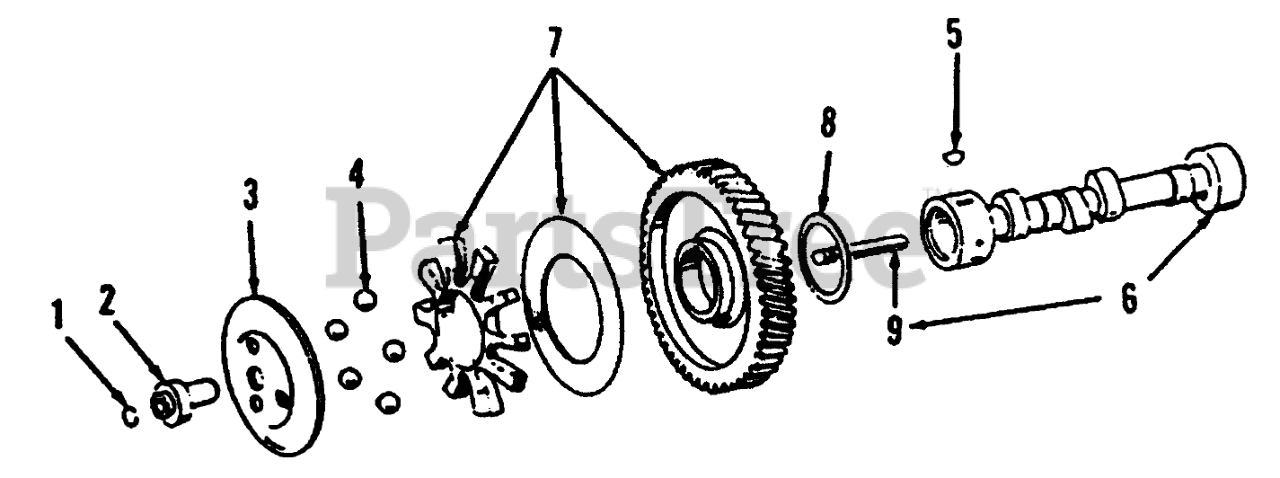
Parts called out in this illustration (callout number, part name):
2	HUB-GOVERNOR CUP
3	CUP-GOVERNOR
4	Ball
6	Camshaft (Includes Center Pin)
8	Washer
9	Pin
